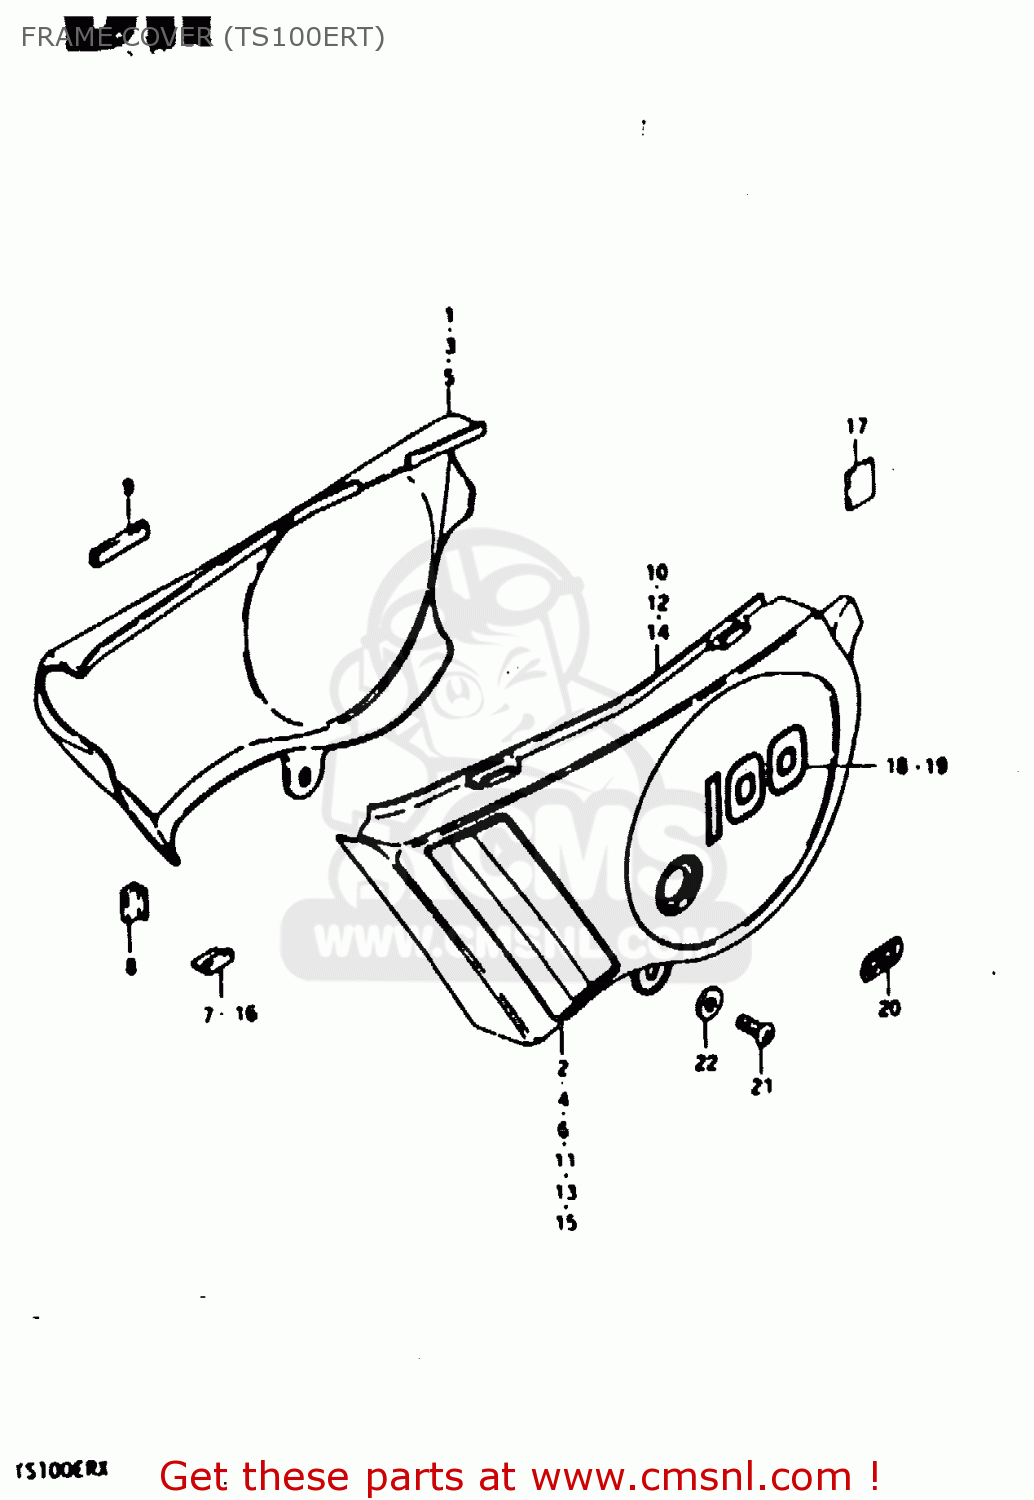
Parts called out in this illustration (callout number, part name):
1	COVER, FRAME RH (RED)
2	TAPE, RH
3	COVER,FRAME,RIGHT
4	TAPE, RH
5	COVER, FRAME RH (WHITE)
6	TAPE, RH
7	CUSHION,FRAME COVER
8	CUSHION,FRAME COVER
9	CUSHION,FRAME COVER
10	COVER, FRAME LH (RED)
11	TAPE, LH
12	COVER,FRAME,LEFT
13	TAPE, LH
14	COVER, FRAME LH (WHITE)
15	TAPE LH
16	CUSHION,FRAME COVER
17	PROTECTOR(170X95X3.0)
18	EMBLEM "100" RH
19	EMBLEM "100" LH
20	EMBLEM,CCIS
21	SCREW 6X12
22	WASHER
